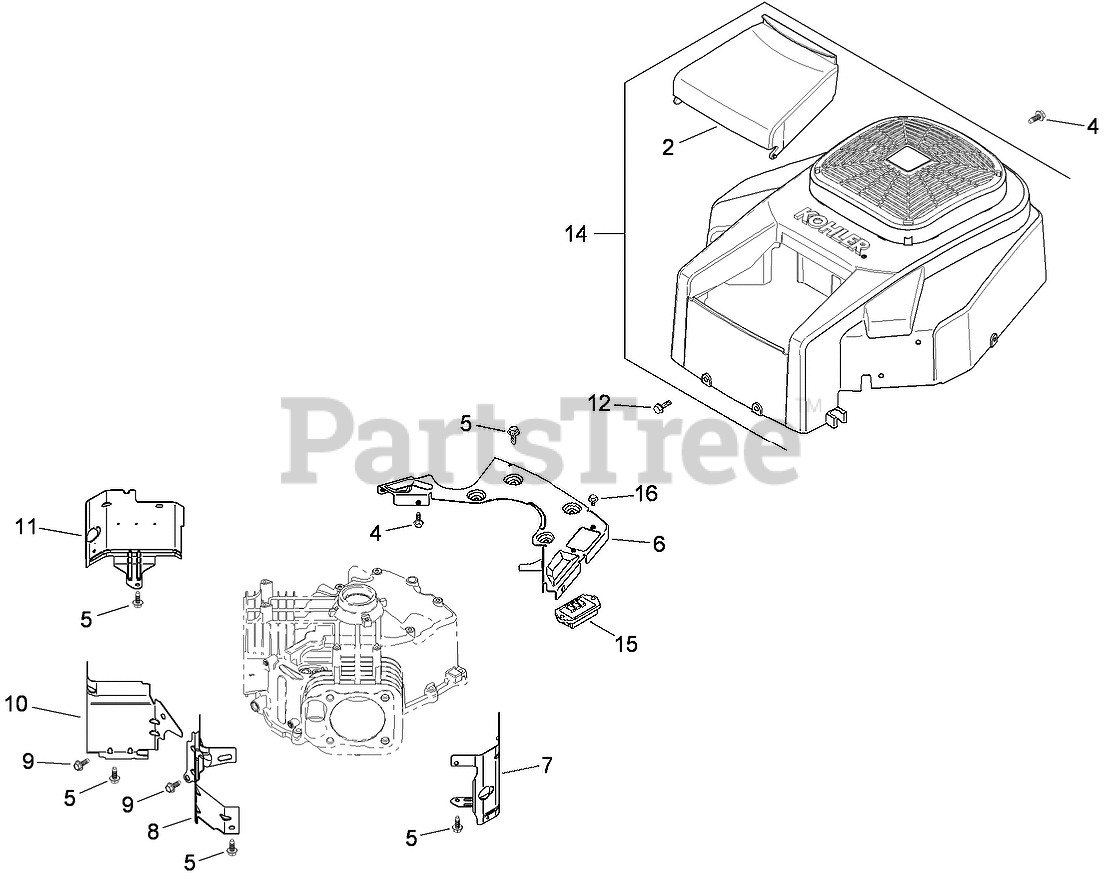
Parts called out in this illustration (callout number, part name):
2	COVER-CLEANER, AIR
4	SCREW-FLANGE, THREAD FORMING (M5X0.8X16)
5	SCREW-FLANGE, THREAD FORMING (M6X1.0X16)
6	PLATE-BACKING
7	BAFFLE-BARREL, CYLINDER (No.2 SIDE)
8	BAFFLE-VALLEY (No.2 SIDE)
9	SCREW-HHFTF (M5X.80X10)
10	BAFFLE-VALLEY (No.1 SIDE)
11	BAFFLE-BARREL, CYLINDER (No.1 SIDE)
12	SCREW-TAP (M6X1.7X18)
14	BLOWER HOUSING ASM (FIXED GUARD) (INCLUDES 2, 41 037 10-S)
15	RECTIFIER/REGULATOR
16	SCREW-FLANGED, THREAD FORMING (M6X1.0X11)
